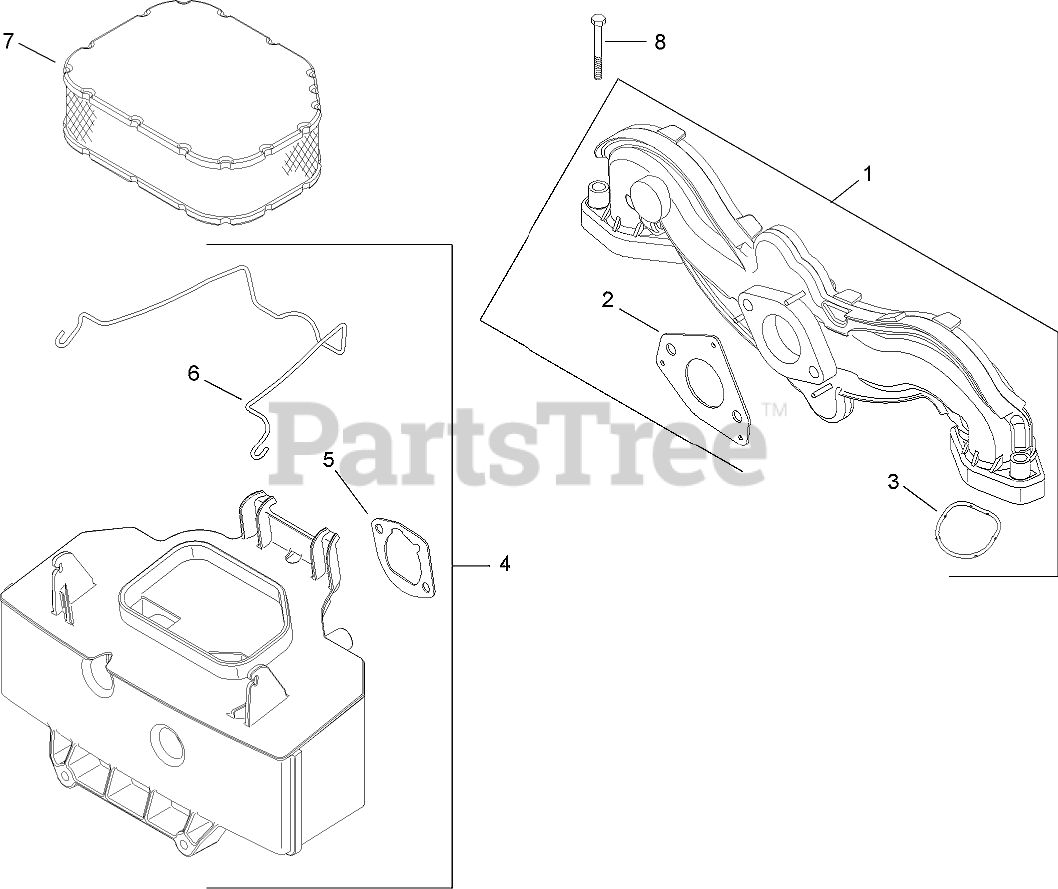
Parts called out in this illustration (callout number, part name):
1	Manifold-Intake (Includes2-3)
2	GASKET-CARBURETOR
3	O-RING
4	Base-Air Cleaner (Includes5-6)
5	GASKET-BASE, AIR CLEANER
6	LATCH-ELEMENT, AIR CLEANER
7	Element-Air Cleaner
8	SCREW-FLANGE (M6X1.0X40)
